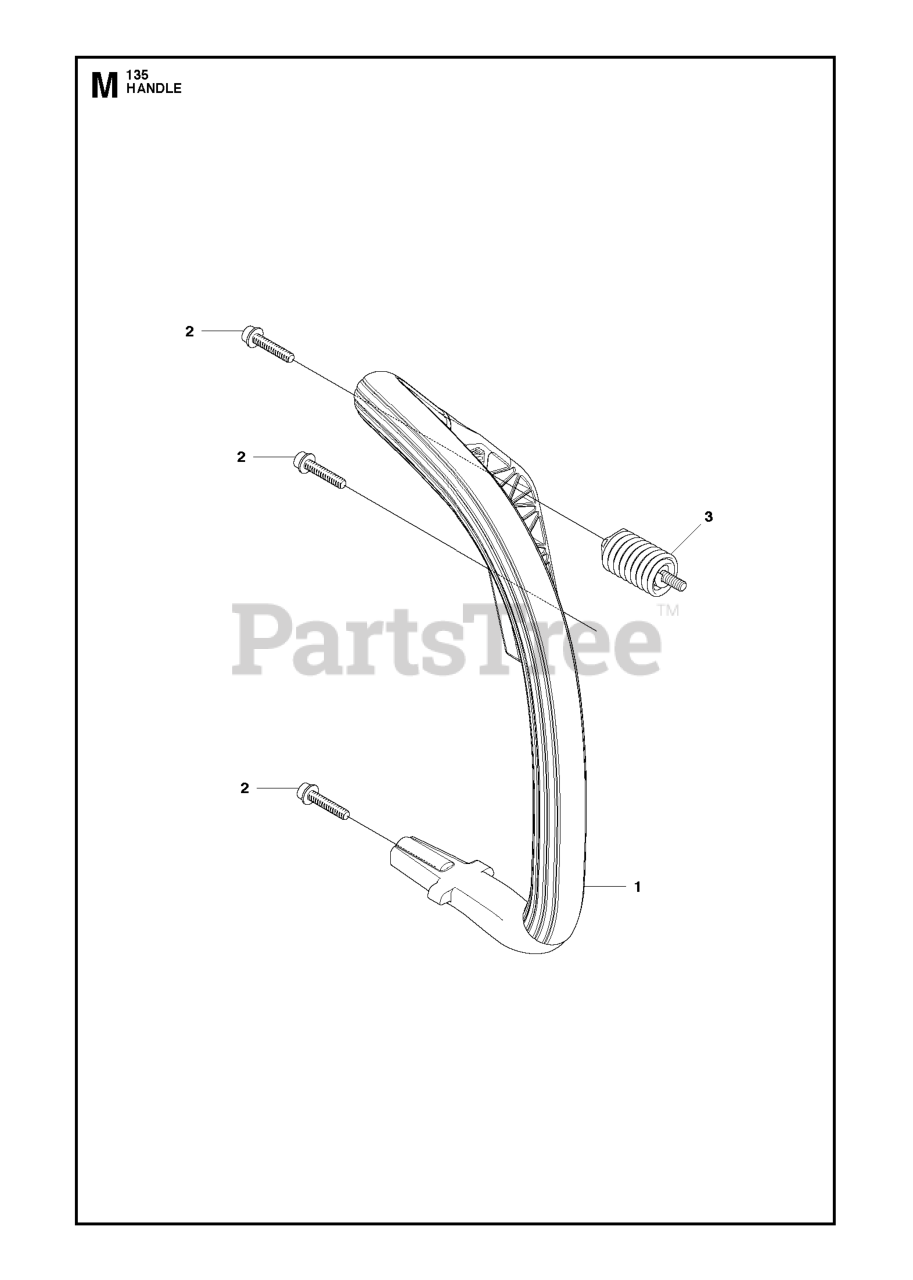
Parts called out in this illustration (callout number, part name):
1	FRONT HANDLE
2	SCREW
3	INSULATOR
